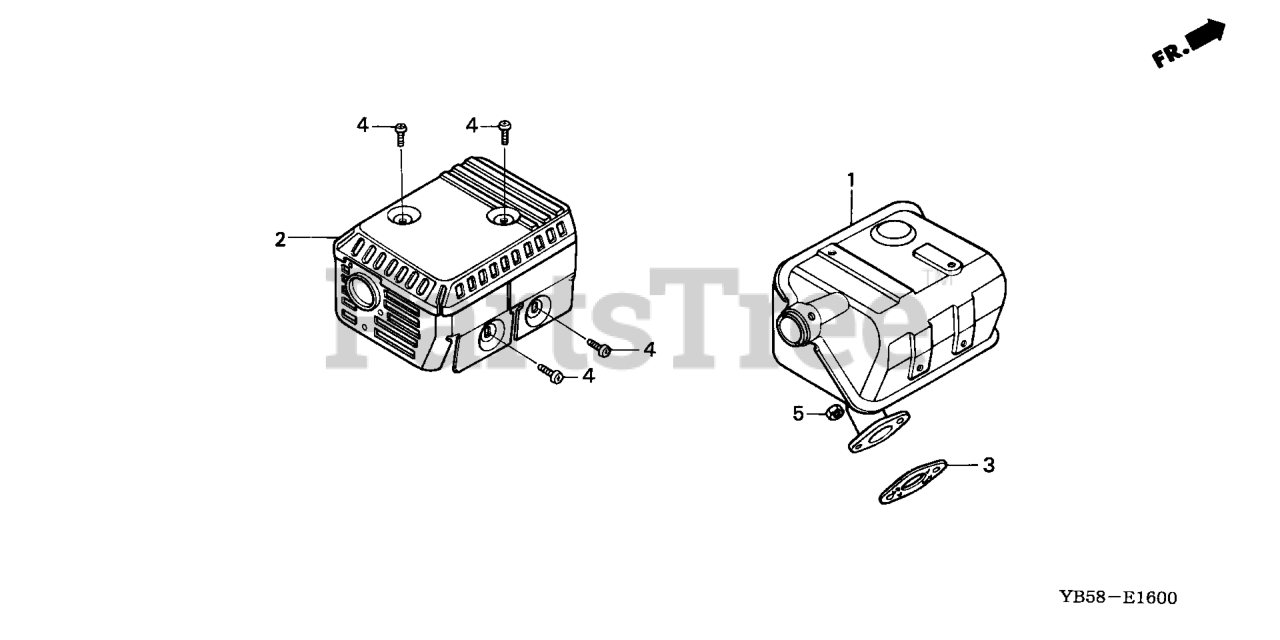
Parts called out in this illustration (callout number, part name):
1	MUFFLER (STD) Use up to Engine SN 1869307.
2	PROTECTOR, MUFFLER (ALUMINIZED)
3	GASKET, MUFFLER
4	SCREW, TAPPING (5X8)
5	NUT, HEX. (8MM)
